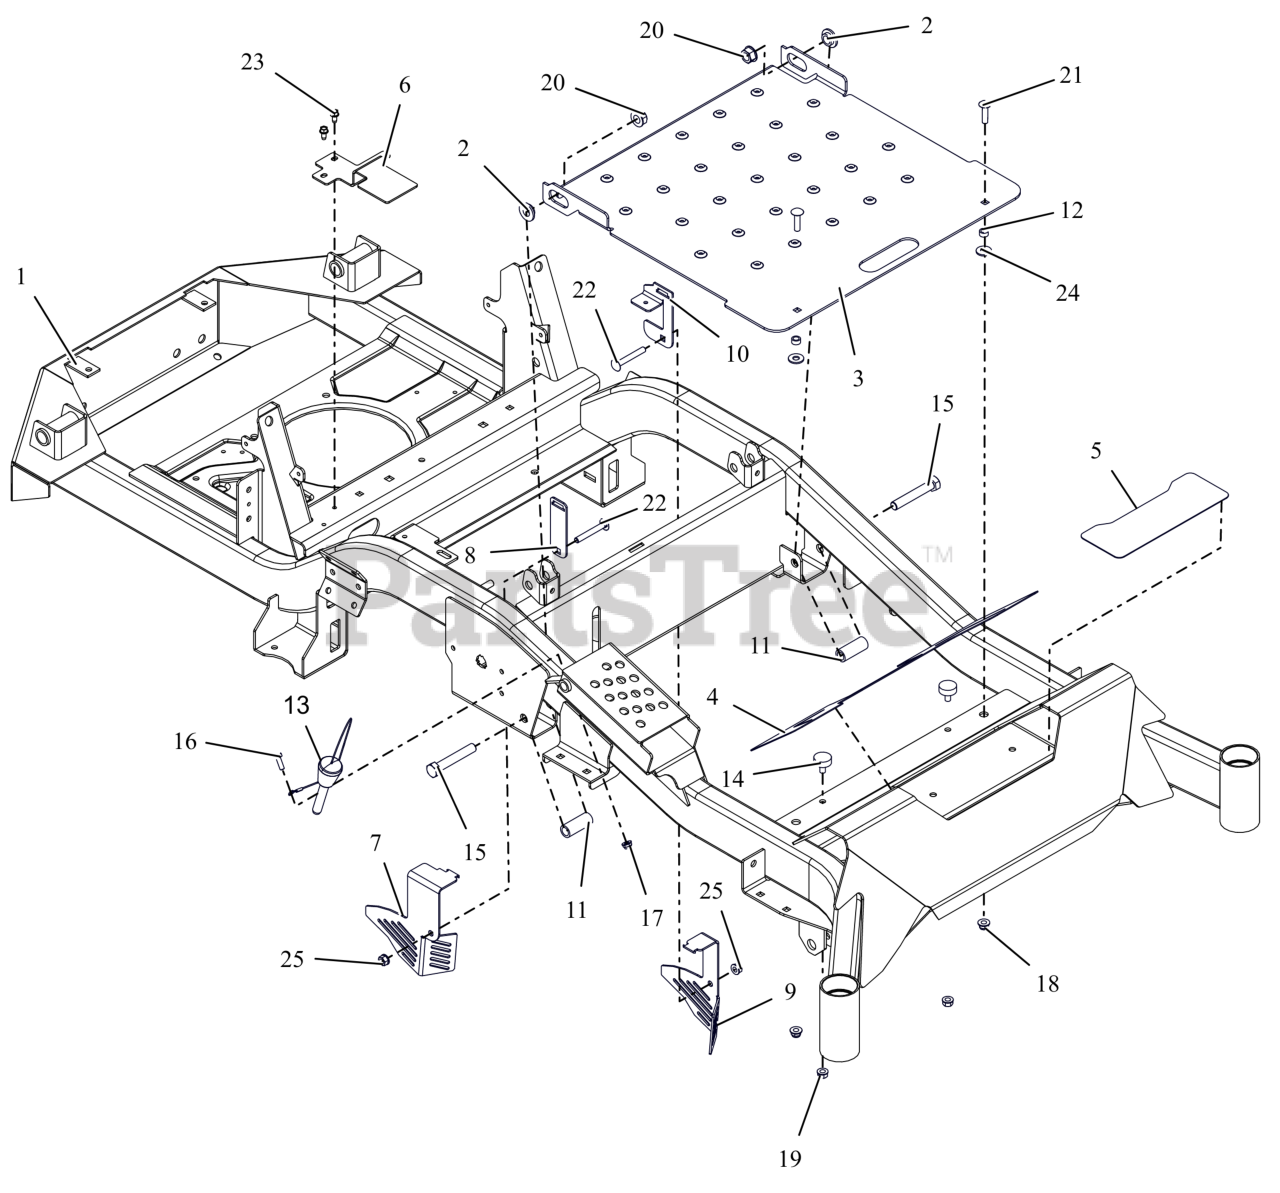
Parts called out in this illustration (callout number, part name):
1	APEX,44-52 FRAME W/SAFETY DECA
2	BSHG-FLG .515X.750X.395X1.120
3	PANEL, ACCESS
4	GRIP, FRONT
5	GRIP, STEP
6	GUARD, TRANSAXLE FAN RH (BLACK)
7	GUARD, TRANSAXLE FAN - RH
8	BRKT, TRANSAXLE FAN GUARD
9	BRKT, TRANSAXLE FAN GUARD-LH
10	MOUNT, TRANSAXLE GUARD
11	SPACER, .515X.75X1.83
12	BSHG-SLV .344 X .500 X .260
13	PIN, MAGNETIC .50X2.50
14	BUMPER, RUBBER
15	BLT, HEX .50-13X3.00 G5 ZCC
16	BLT, HEX .25-20X.75 G5 ZCC
17	NUT,NYL-FLG .25-20 GF ZCC
18	NUT,LK-NYL-FLG .31-18 G5ZC120
19	NUT,SPNLK-FLG .31-18 G5 ZCC
20	NUT-LK-TOP-FLG .500-13 GF ZCC
21	BLT, RHSSN.31-18X1.25 G5 ZCC
22	BLT, RHSSN.31-18X2.25 G5 ZCC
23	SCR-TAP .25-20X.50 HWH ZCC
24	WSHR,FLT .375X.875X.083 ZCC
25	NUT,LK-CTR-FLG .31-18 GF ZCC
